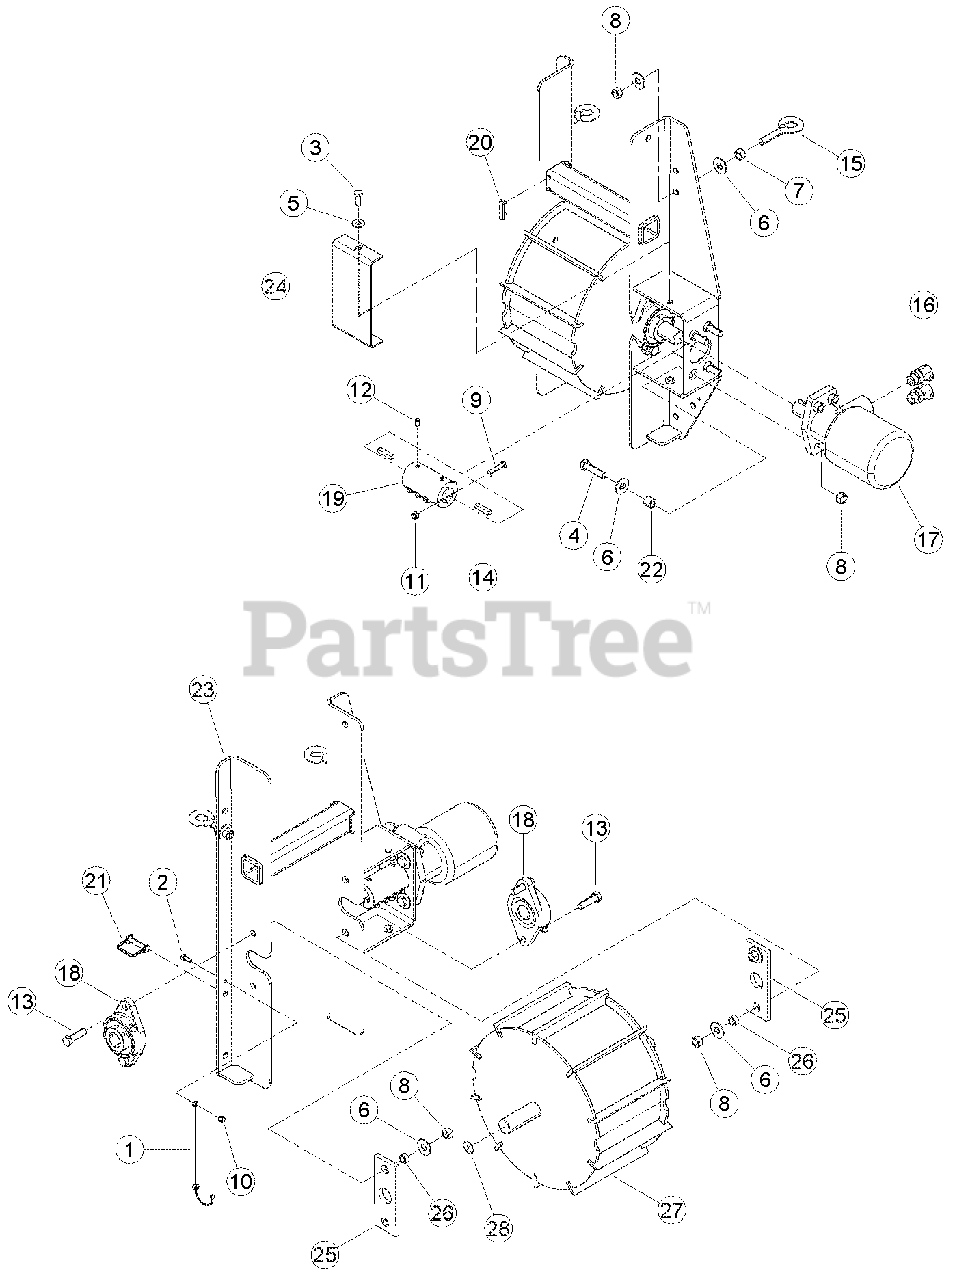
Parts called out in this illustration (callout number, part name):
1	LANYARD, NYLON
2	BOLT, 1/4 X 3/4 HEX HD GR5 ZP
3	BOLT, 3/8 X 1 HEX HD GR5 ZP
4	BOLT, 1/2 X 2 HEX HD GR5 ZP
5	WASHER, 3/8 FLAT ZP
6	WASHER, 1/2 FLAT ZP
7	NUT, 1/2 HEX NC ZP
8	NUT, 1/2 CENTERLOCK GRB ZP
9	BOLT, 5/16 X 1-1/2 HEX HD GR5 ZP
10	NUT, 1/4 NE NYLOCK ZP
11	NUT, 5/16 NE NYLOCK ZP
12	SET SCREW, 3/8 X 1/2 CUP PT SKT
13	BOLT, 1/2 X 1-3/4 HEX HD GR5 NC ZP
14	KEY, 5/16 SQUARE X 1-1/2 LONG
15	EYEBOLT, 1/2 X 2 ZP
16	ADAPTER, -10 MORING / -8 MJIC 45 DEG.
17	MOTOR, 45 CU IN HYDRAULIC
18	BEARING, 1-1/4" DIA 2 BOLT FLANGE
19	COUPLER, 1-1/4 SHAFT
20	WEAR PAD, STD. SPRING HD FRONT
21	PIN, SNAP 3/8 X 1-1/2 USABLE LENGTH
22	SPACER,0.75 X 0.620
23	WELDMENT, ROLLER SLIDE
24	SHIELD, COUPLER
25	BEARING, SLIDE
26	SPACER, .75 OD X .5 ID X .37
27	ASSEMBLY, TOP GRAB ROLLER, SERVICE PART
28	DECAL, ROTATING SHAFT
